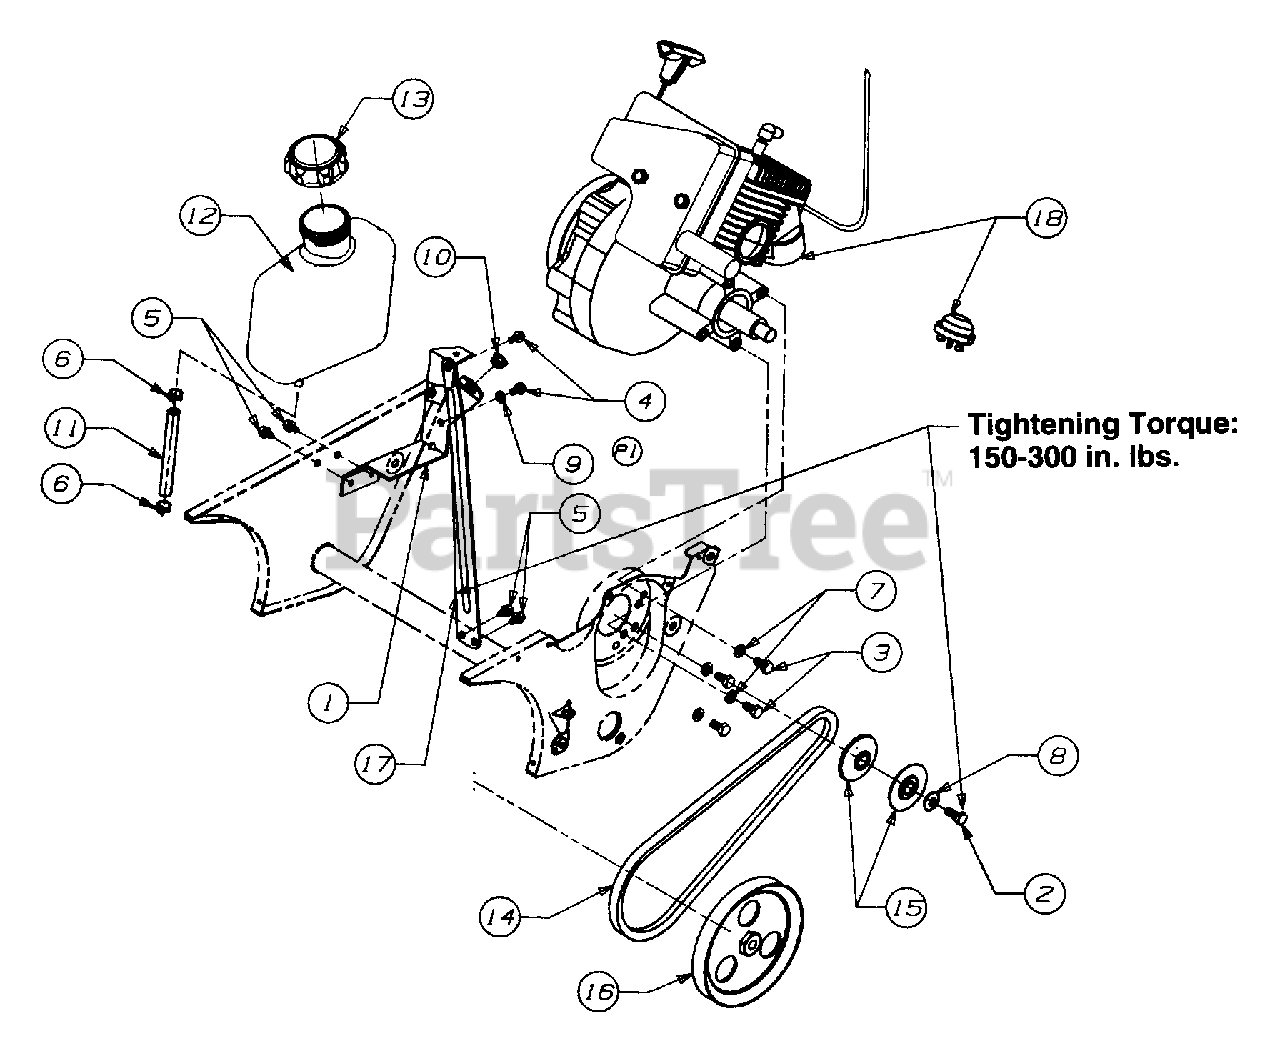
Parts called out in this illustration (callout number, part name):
1	Bracket Tank Support
2	Screw Hex
3	Screw Hex
4	Screw Hex Wash SF
5	Screw Hex
6	Clamp Hose
7	Washer Lock
8	Washer Bell
9	Washer Lock
10	Bushing
11	Hose-Fuel Line (16")
12	Tank Gas (2 Qt.)
13	Cap Fuel
14	V-Belt
15	Pulley Half
16	Pulley
